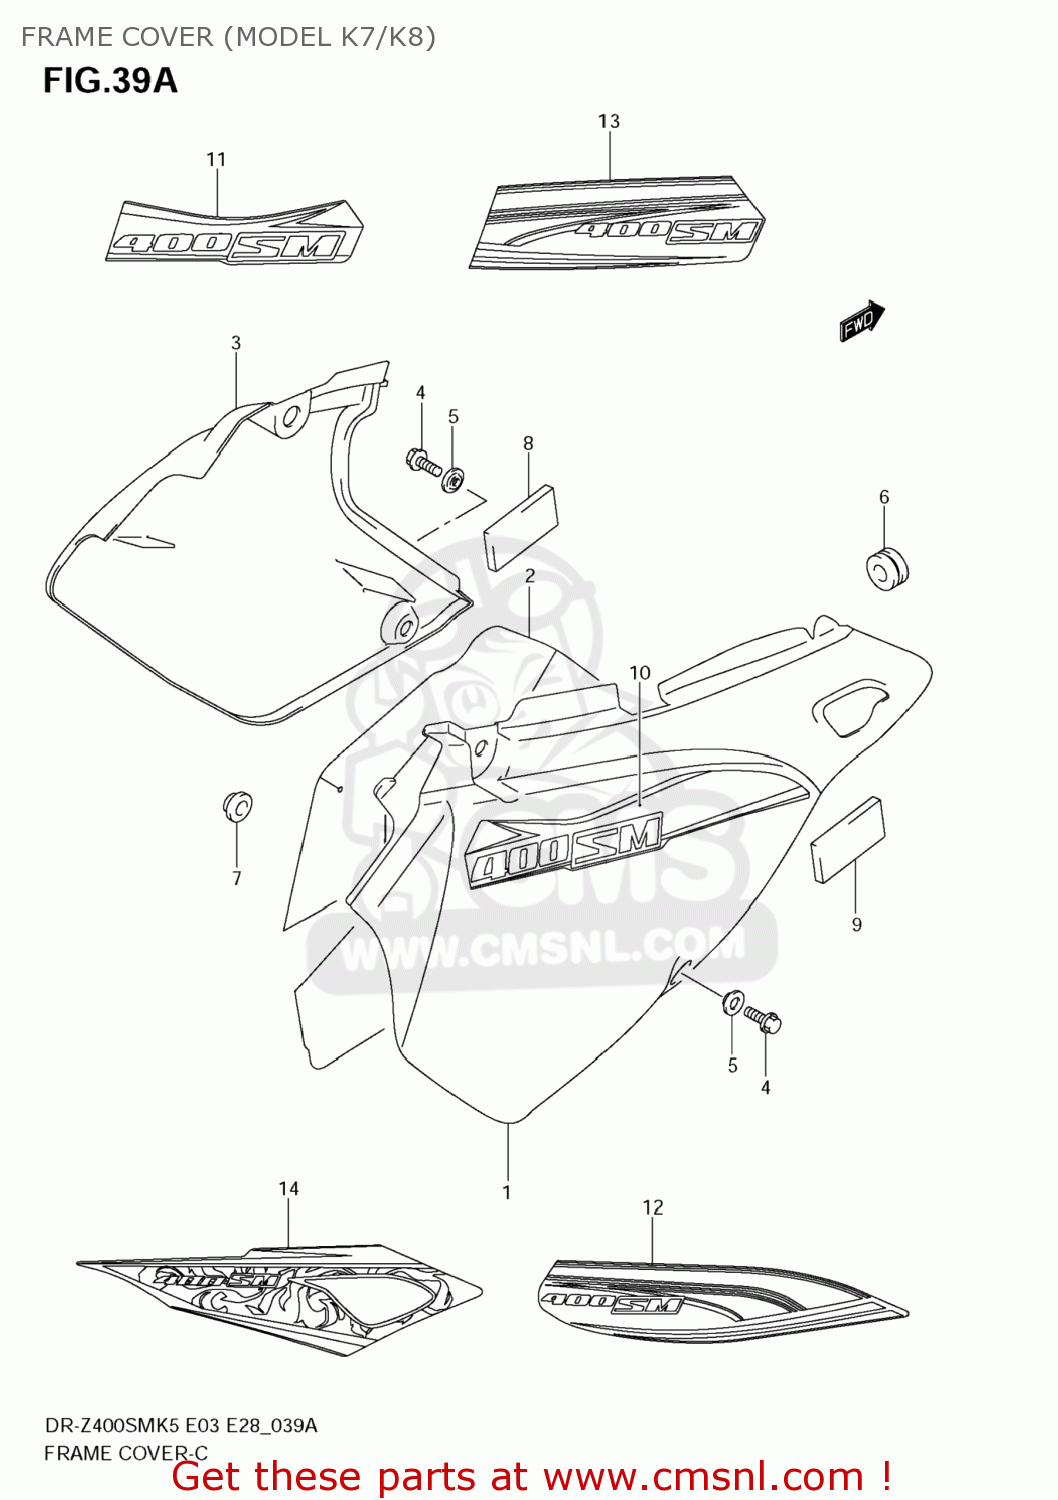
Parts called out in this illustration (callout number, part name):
1	COVER,FRAME,R(BLACK)
2	SHIELD,FRAME COVER,R
3	COVER,FRAME,L(WHITE)
4	BOLT(6X12)
5	WASHER
6	CUSHION
7	CUSHION
8	CUSHION,FRAME COVER,L
9	CUSHION
10	TAPE,FRAME COVER,R
11	TAPE,FRAME COVER,L
12	TAPE,FRAME COVER,R
13	TAPE,FRAME COVER,L
14	TAPE,FRAME COVER,R
